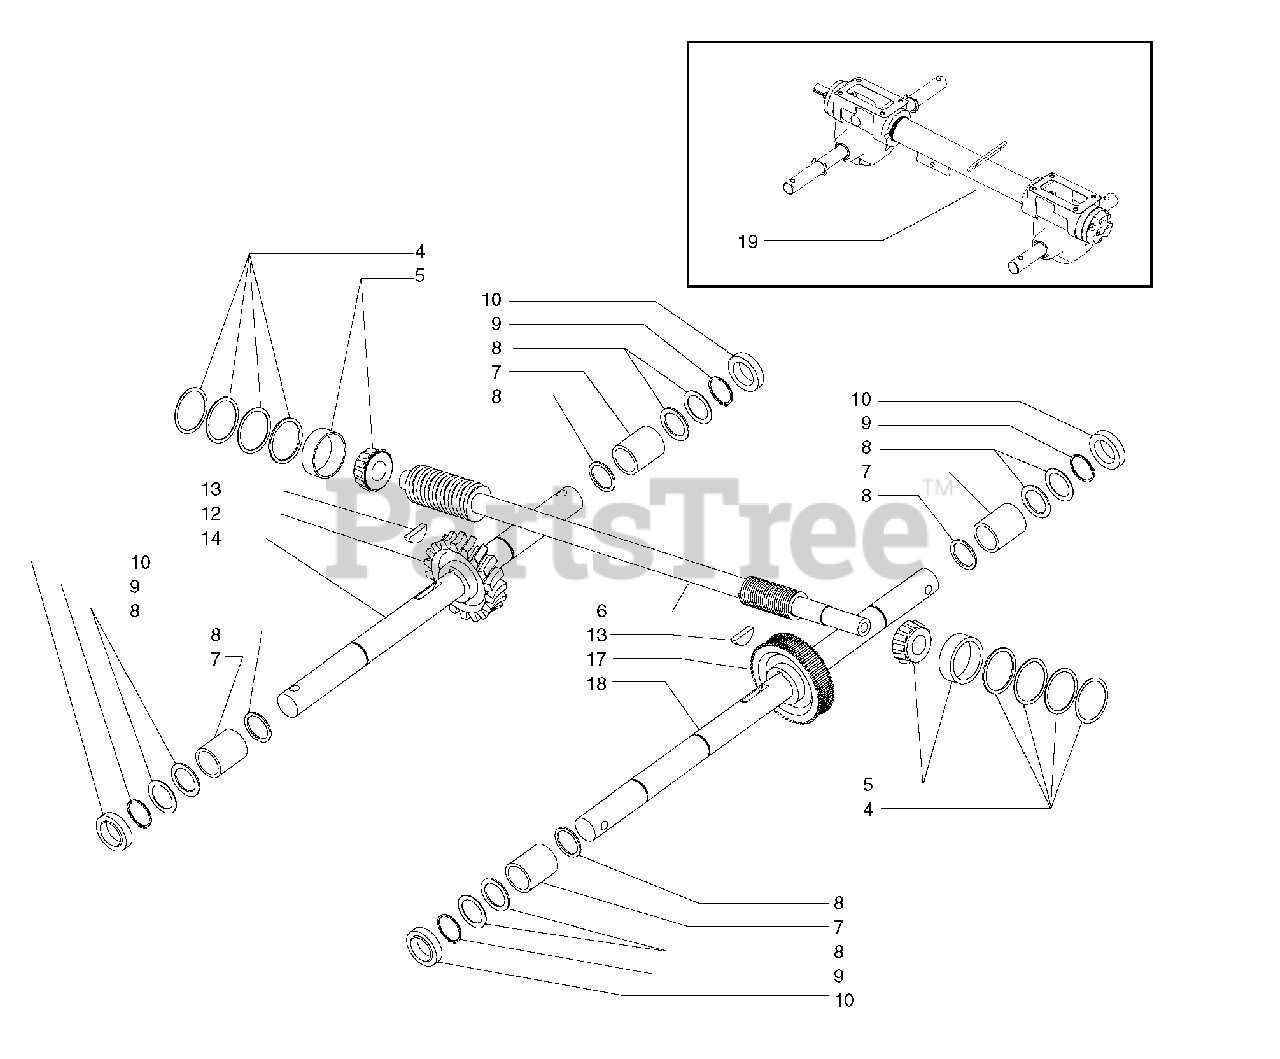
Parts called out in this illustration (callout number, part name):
4	* SHIM, Drive shaft
5	* BEARING, Tapered Roll
6	* SHAFT, Drive SRT
7	* BUSHING
8	* SPACER, 1" ID x 1-1/4 OD
9	RING, Retainer Shaft
10	SEAL, Oil, Housing
12	* GEAR, Tine, SRT
14	* SHAFT, Tine
17	* GEAR WHEEL
18	* SHAFT, WHEEL, Long
19	TRANSMISSION ASSEMBLY
